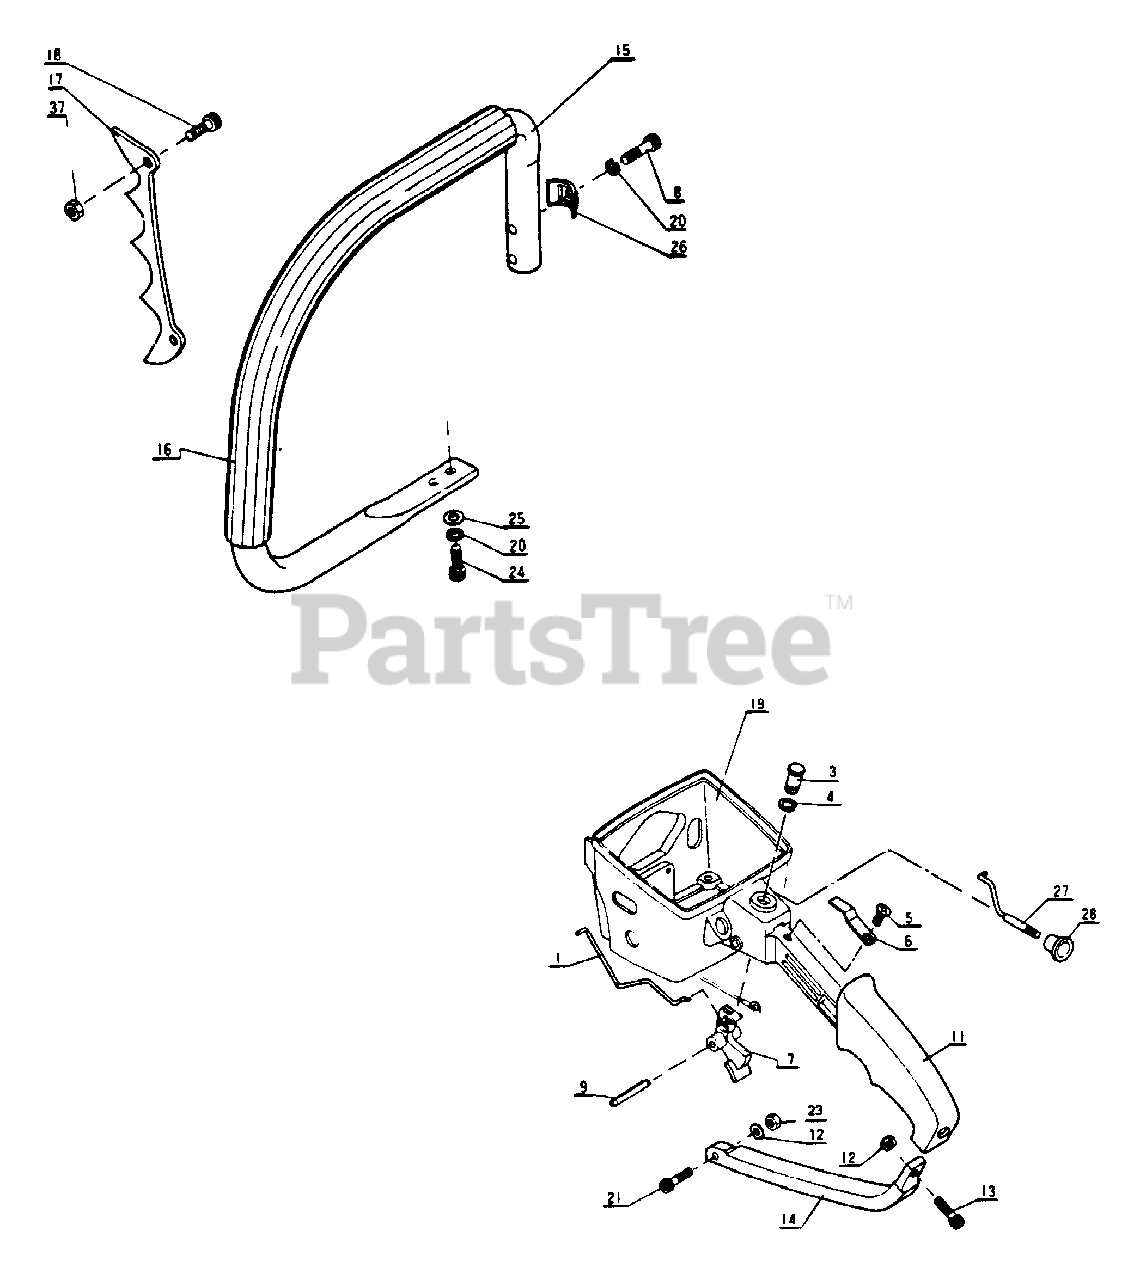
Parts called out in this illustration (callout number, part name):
1	ROD, CHOKE
3	LOCKOUT, THROTTLE
4	RING, RETAINING - 6
5	SCREW
5	SCREW - 5X8
6	SPRING, TRIGGER
7	TRIGGER, THROTTLE
8	BOLT
11	COVER, HANDLE
12	NUT
12	NUT - 5
13	SCREW - 5X25
13	BOLT - 5X25
14	SUPPORT, HANDLE
15	HANDLE - FRONT
16	HANDLE - FRONT
17	SPIKE
18	SCREW - 5X18
18	BOLT - 5X18
19	HANDLE - RIGHT
20	LOCKWASHER - 6
21	SCREW - 5X30
21	BOLT - 5X30
23	NUT
23	LOCKNUT - 5
24	BOLT
25	WASHER - 6
26	Handle set plate
27	ROD, CHOKE
28	BUTTON, OIL PUMP
37	NUT
